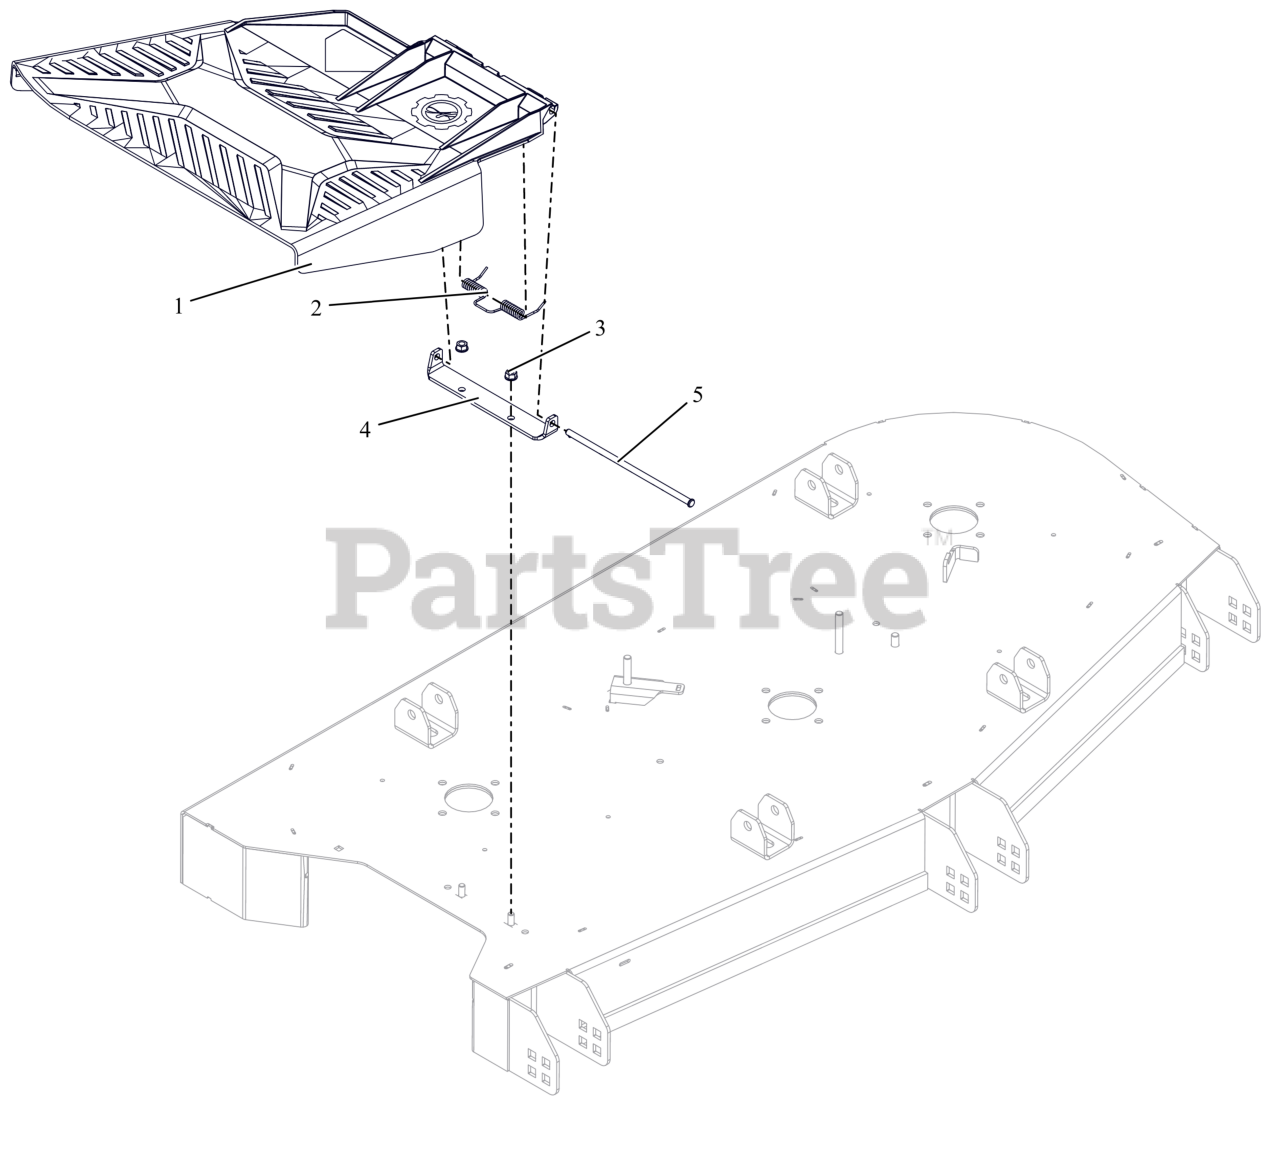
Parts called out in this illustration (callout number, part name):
1	CHUTE- SIDE DISCHARGE
2	SPRING-TORSION
3	NUT,LK-CTR-FLG .31-18 GF ZCC
4	BRKT, DISCHARGE CHUTE (MATTE BLACK)
5	PIN- SLIC .312X8.50
